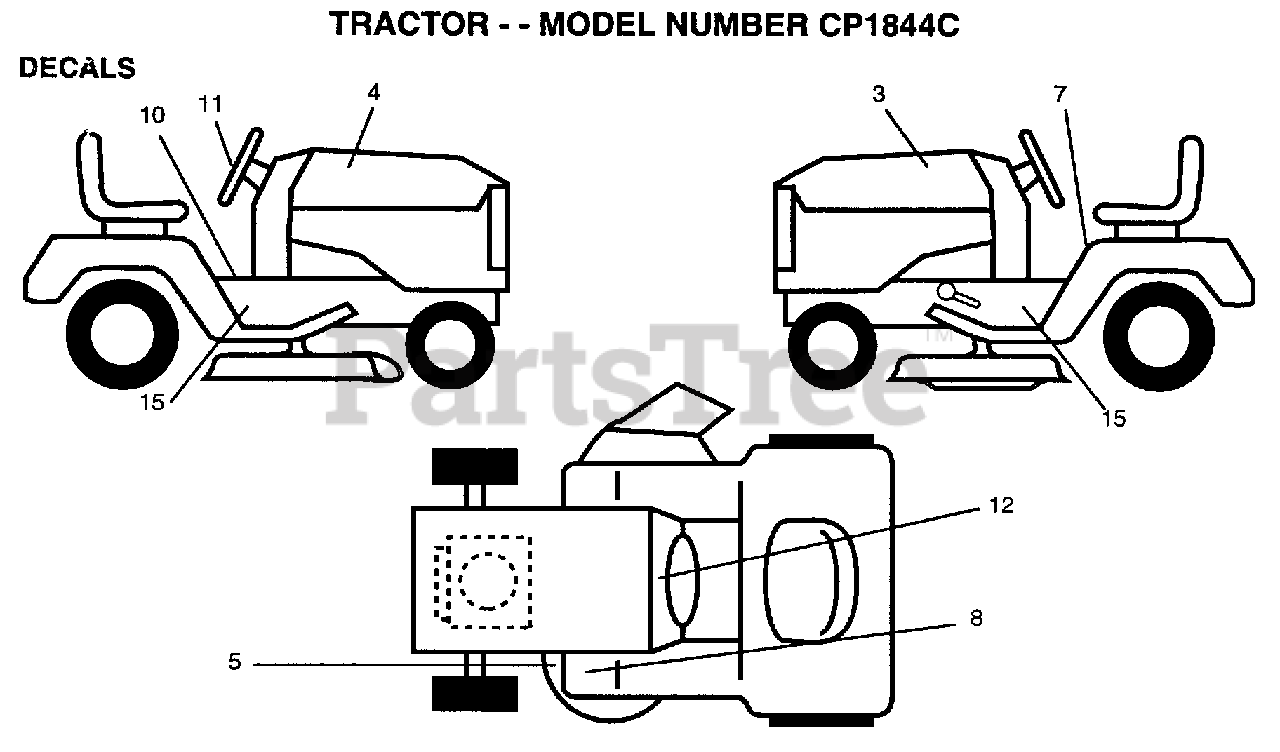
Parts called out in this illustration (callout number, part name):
4	DECAL HOOD STRIPE RH
5	"DECAL.V.BELT.44"""
7	DECAL
10	DECAL BRAK PARK
11	DECAL.WHL.STRG.
12	DECAL.DASH.INSTR.
